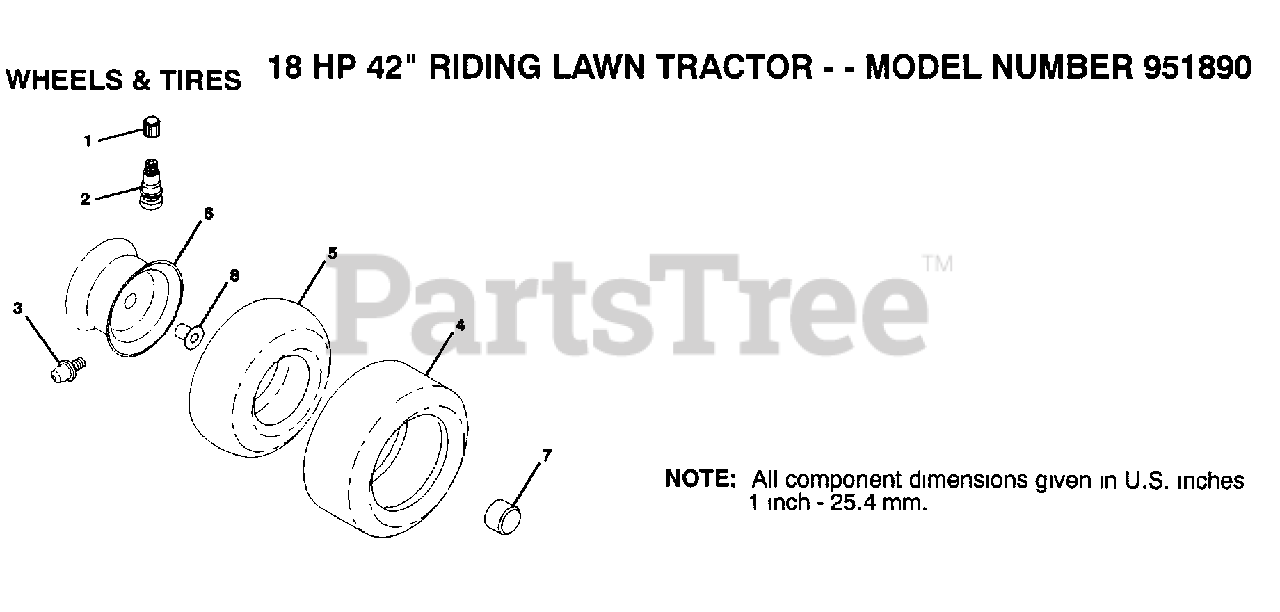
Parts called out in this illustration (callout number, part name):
1	VALVE CAP
2	VALVE STEM LT
3	FITTING LT
4	TIRE TM 15X6X6
4	TIRE TM 20X8X8
5	TUBE.5.3/4.5/6
5	TUBE.18X9.5-8
7	HUB CAP
8	"FLANGE, BEARING"
